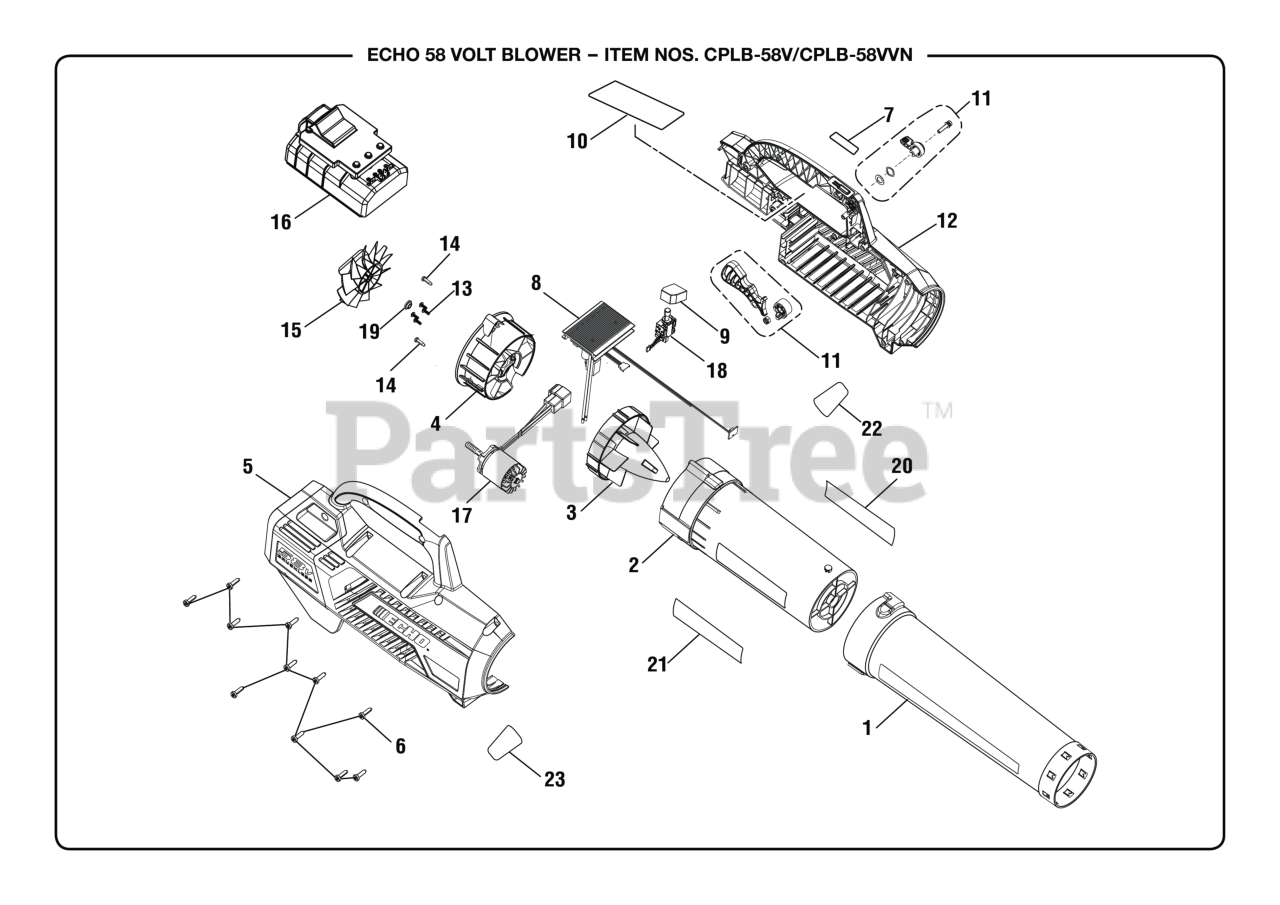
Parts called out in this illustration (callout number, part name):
1	Nozzle & Scraper Assembly
2	Outlet Housing
3	Tailcone
4	Guide Vane Assembly
5	Right Housing Assembly
6	Screw (M5 x 17.5 mm, T20 Torx Pan Hd.)
7	Turbo Boost Label
8	Circuit Board
9	SWITCH PLATE
10	Warning Label
11	Cruise Control Lever Assembly
12	Left Housing Assembly
13	Screw (M3 x 8 mm, Pan Hd.)
14	Screw (M4 x 13.5 mm, T15 Torx Pan Hd.)
16	Battery Carriage
17	Motor Assembly
18	Variable Signal Switch
19	BUSHING
20	Fan Label (Left)
21	Fan Label (Right)
22	Data Label
23	Data Label
